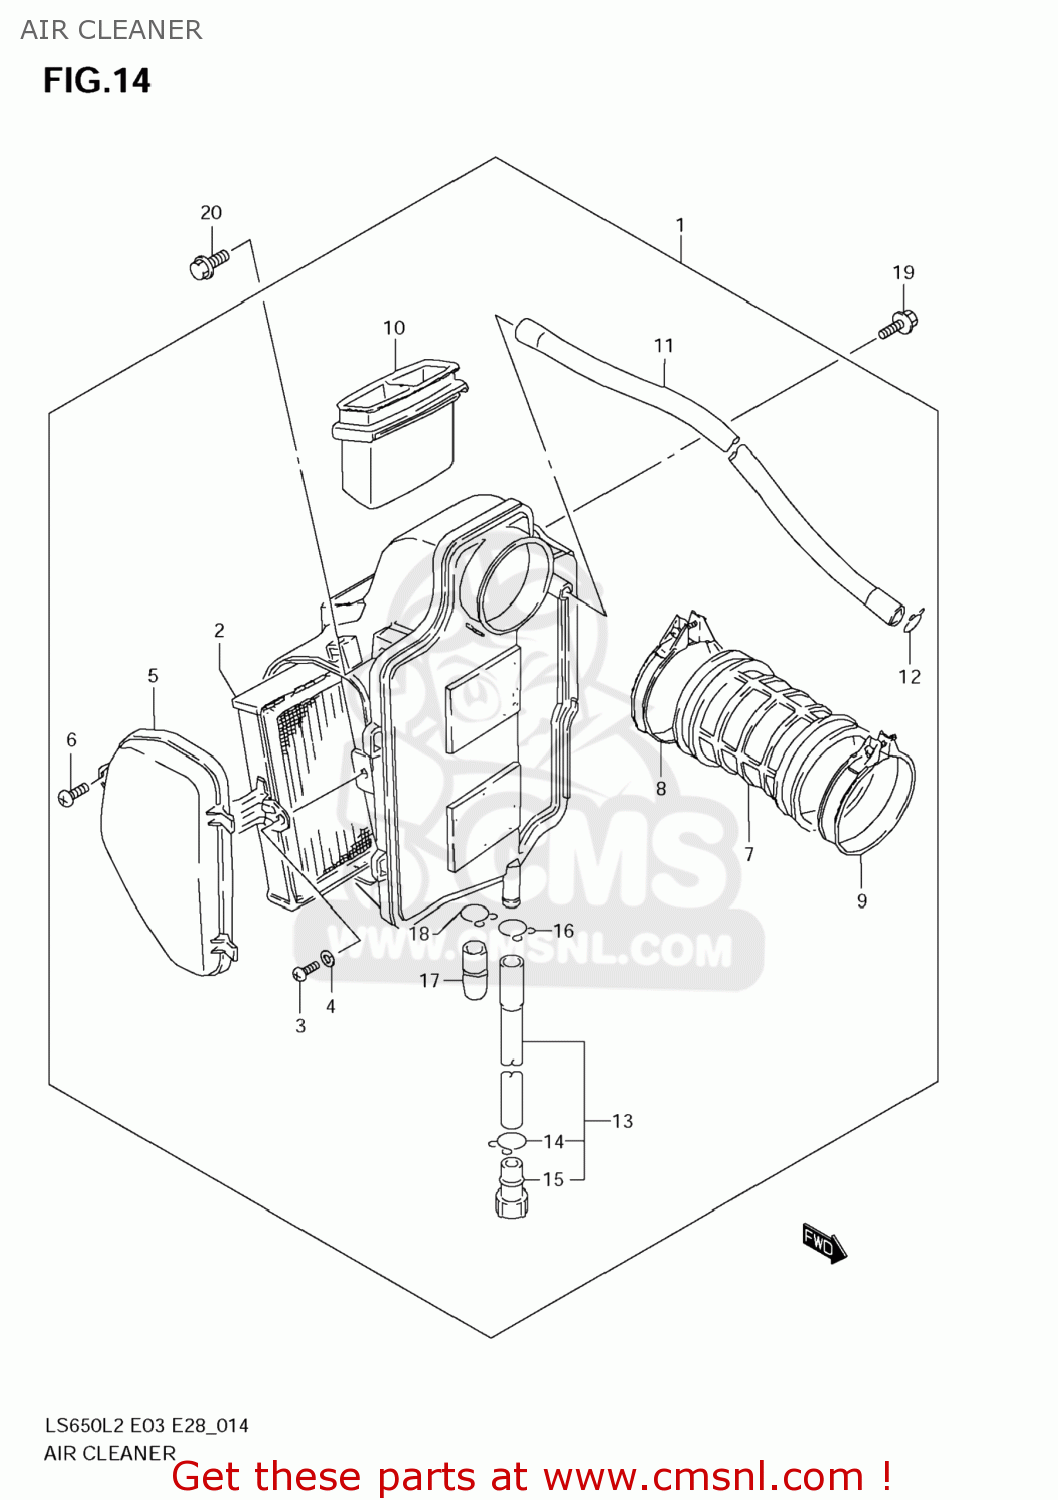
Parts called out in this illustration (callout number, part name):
1	CLEANER ASSY,AIR
2	FILTER ASSY,AIR
3	SCREW
4	WASHER,LOCK
5	CAP,AIR CLEANER
6	SCREW
7	TUBE,AIR CLEANER OUTLET
8	CLAMP
9	CLAMP
10	TUBE,INLET
11	HOSE(11X15X600)
12	CLIP
13	TUBE,DRAIN
14	CLIP
15	STOPPER,DRAIN
16	CLIP
17	PLUG
18	CLIP
19	BOLT(6X16)
20	BOLT
